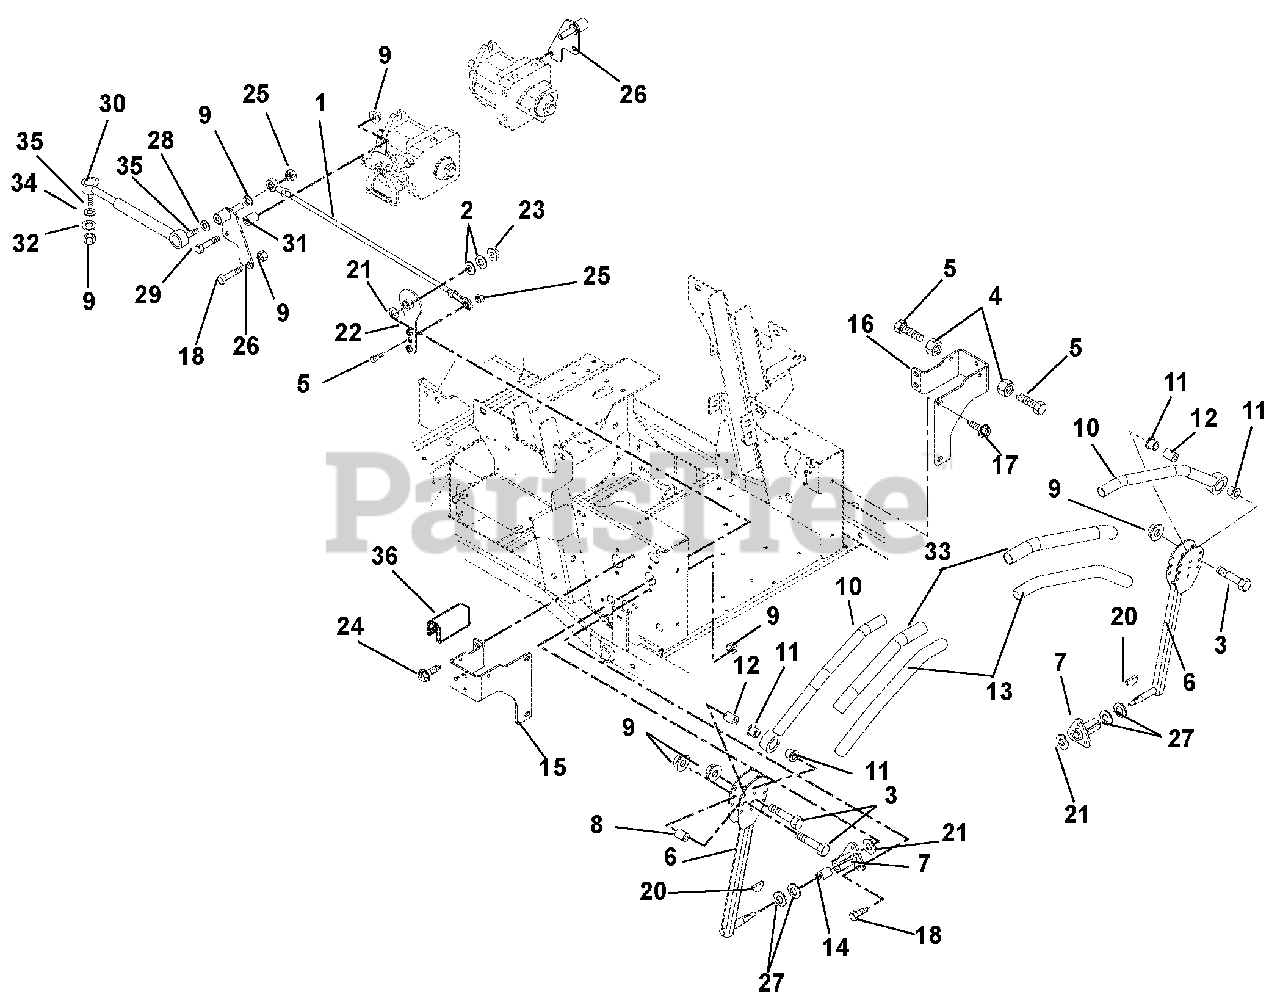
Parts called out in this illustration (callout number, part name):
1	Assembly, Steering Rod .38 Rod x 21.65
2	Washer, Flat Steel .408 x .812 x .065
3	Bolt, Hex .31-18 x 1.75 Grade 5
4	Nut, Hex Jam .375-16
5	Bolt, Hex .375-16 x 1.75
6	Weldment, Control Arm
7	Bushing, Flange
8	Bushing, Eccentric .31 x .75 x .97
9	Nut, Locking Top Flange .31-18
10	Handle Weldment, Left Hand
11	Bushing, Flange Nylon .762 x 1.48 x .44
13	Grip, Handlebar
14	Bushing .625 x .75 x .50
15	Bracket, Stop Right Hand
16	Bracket, Stop Left Hand
17	Screw, Tapping Hex Washer Head .38-16 x .75
18	Bolt, Hex .31-18 x .75 Grade 5
19	Washer, Locking .38 x .094 Regular
20	Key, Woodruff .13 x .63
21	Washer, Wave
22	Weldment, Pivot Arm
23	Nut, Locking Top Flange .38-16
24	Screw, Tapping Hex Washer Head .38-16 x .50
25	Nut, Locking-Jam-Center .375-16
26	Weldment, Return to Neutral/Damper/Rod End
27	Washer, Flat Steel .63 x 1.005 x .062
28	Washer, Locking .31 x .078
29	Bolt, Hex .31-18 x 1.25 Grade 5
30	Damper, Control
31	Spacer .318 x .43 x .375
32	Washer, Flat Steel .38 x .875 x .083
33	Tube, .88 ID x 1.00 OD x 10.7
34	Washer, Flat Steel .328 x 1.00 x .094
35	Stud, Ball
36	Strip Cowl
